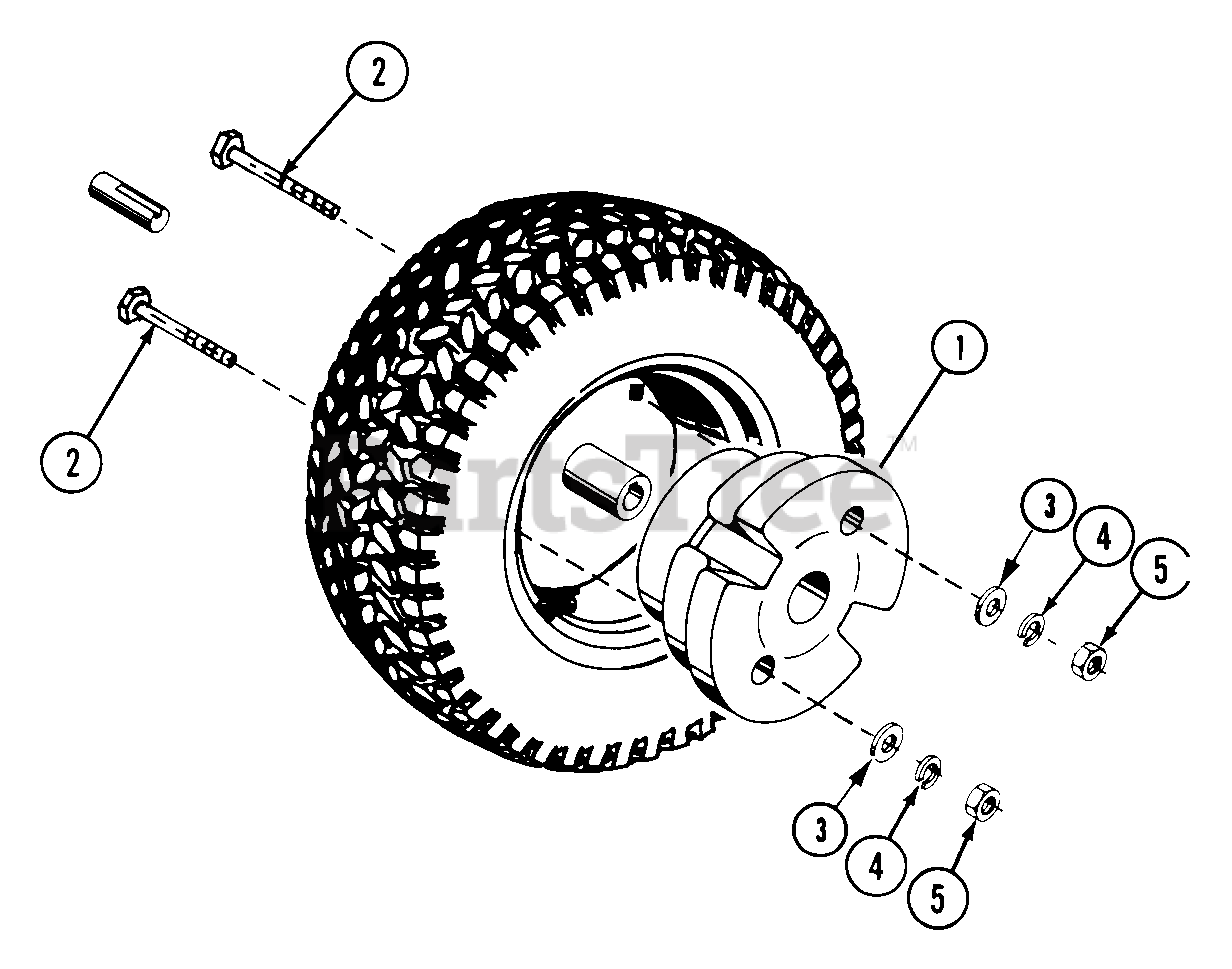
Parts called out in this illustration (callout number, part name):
1	WHEEL WEIGHT
2	BLT-HEX .38-16X5.00 PL GR2
3	WSHR-FL-STL .38X.875X.083 PL
4	WSHR-LK .375X.115 HVY PL
5	NUT-HEX .375-16
